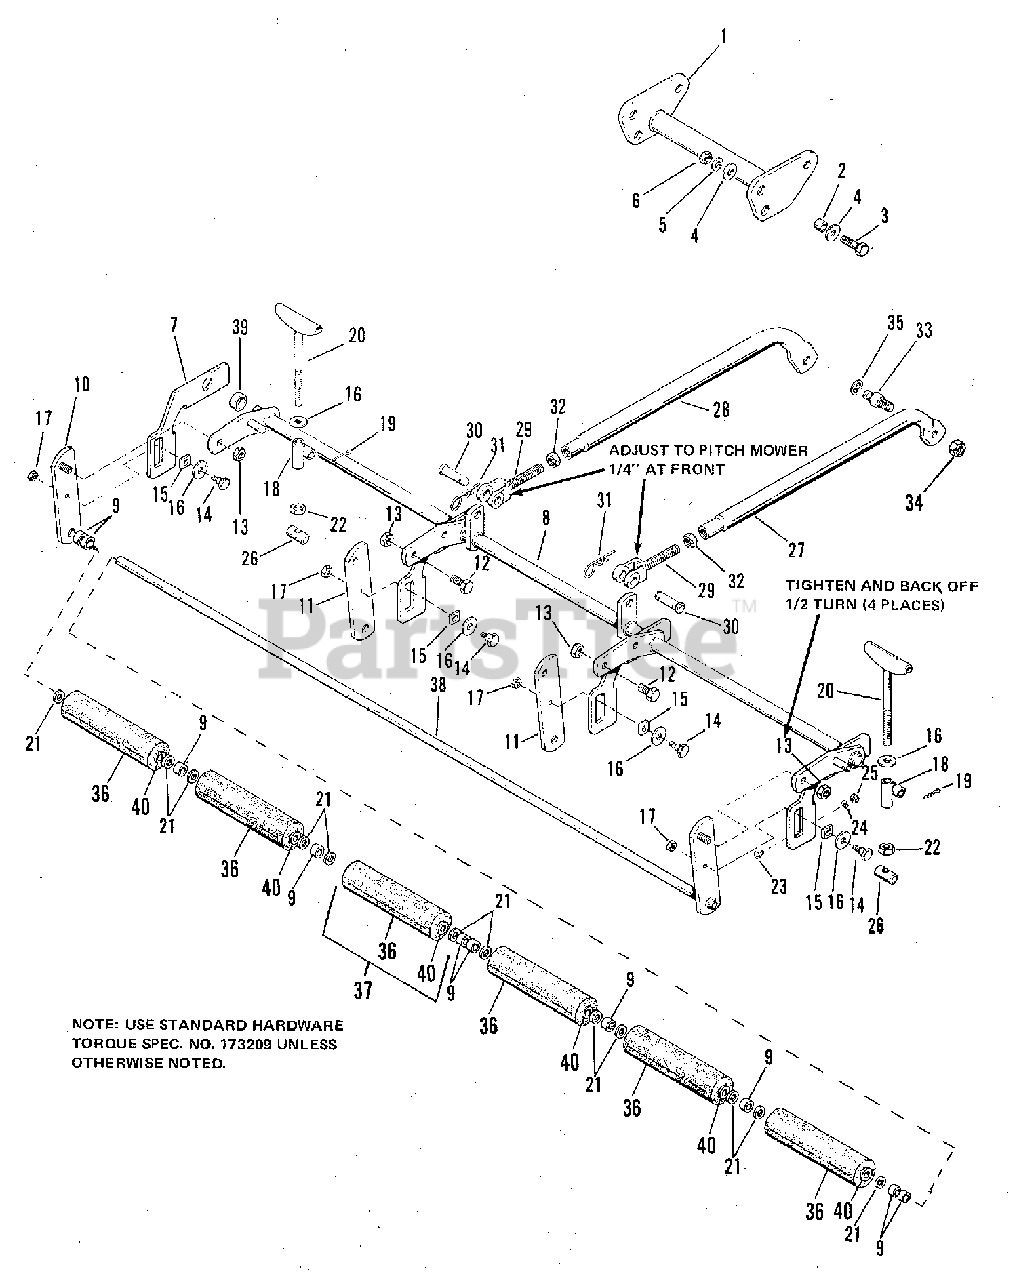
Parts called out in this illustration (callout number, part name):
1	ARM ASSY, Rocker
3	CAPSCREW, Hex Hd, 1/2-13 x 1-3/4
4	WASHER, Plain, 7/16
5	LOCKWASHER, Spring, 1/2
6	NUT, Hex, 1/2-13
7	BRACKET, Roller
8	ROCKER ASSY, Arm
10	BAR ASSY, Roller
11	BAR, Roller
12	CAPSCREW, Hex Hd., 1/2-13 x 1-1/4
13	NUT, Hex, Lock, 1/2-13
14	BOLT, Shoulder, 3/8-16 X 1.34
16	WASHER, Plain, 1/2
17	NUT, Hex, Lock, Jam, 3/8-16
18	PIVOT ASSY
19	PIN, Cotter, 3/16 x 1
20	SCREW ASSY, Adj,
22	NUT, Hex, Full Lock, Jam, 1/2-13
23	BOLT, Rd. Hd., Sq. Nk., 5/16-18 x 3/4
24	LOCKWASHER, Spring, 5/16
25	NUT, Hex, 5/16-18
26	PIN, Cotter
27	BAIL, R.H.
28	BAIL, L.H.
30	PIN, Yolk
31	PIN, Quick, 1-7/8
32	NUT, Hex, Lock, Jam, 5/8-18
33	BOLT, Shoulder, Special
34	NUT, Hex, Jam, Finished, 5/8-11
35	RING, E, External
37	ROLLER, w/Bushings
38	SHAFT ASSY, Roller
